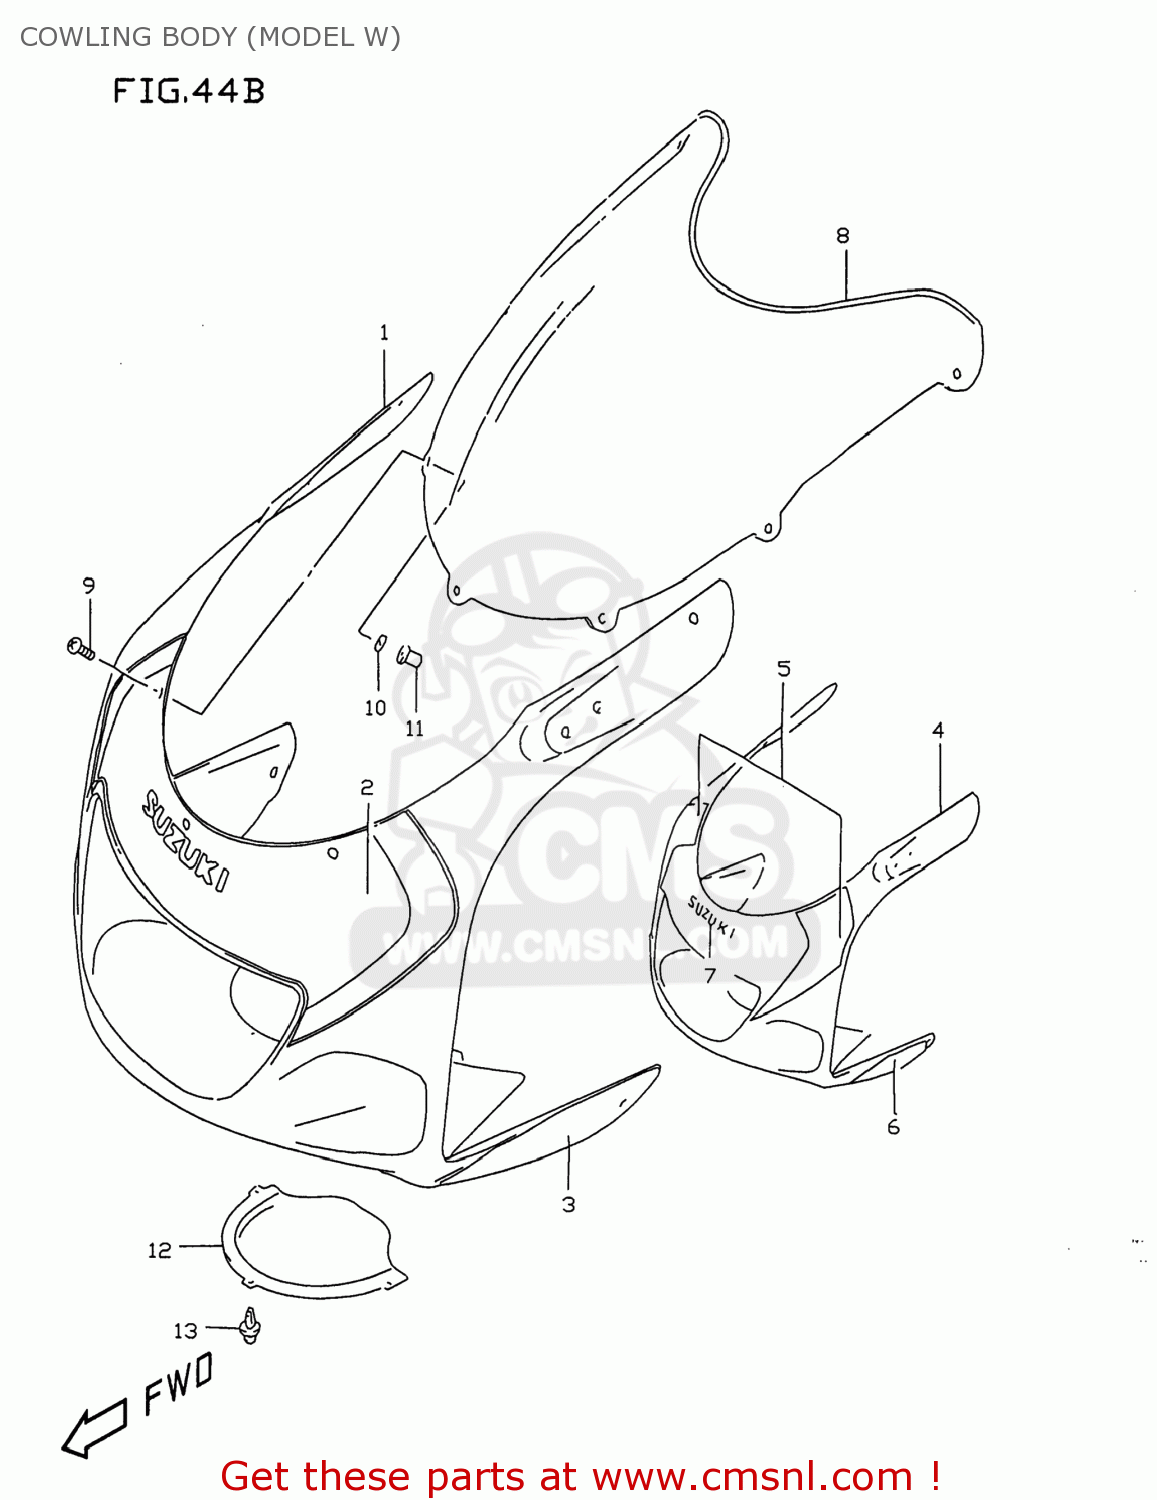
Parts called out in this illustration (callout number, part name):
1	COWLING ASSY,BODY
2	TAPE,COWLING BODY,FRONT
3	TAPE SET,COWL BODY SIDE
4	COWLING ASSEMBLY,BODY
5	TAPE SET,COWLING BODY
6	TAPE SET,COWL BODY SIDE
7	EMBLEM,SUZUKI
8	WINDSCREEN
9	SCREW(5X14)
10	WASHER
11	NUT
12	LID,BODY COWL LWR
13	CLIP(BLACK)
